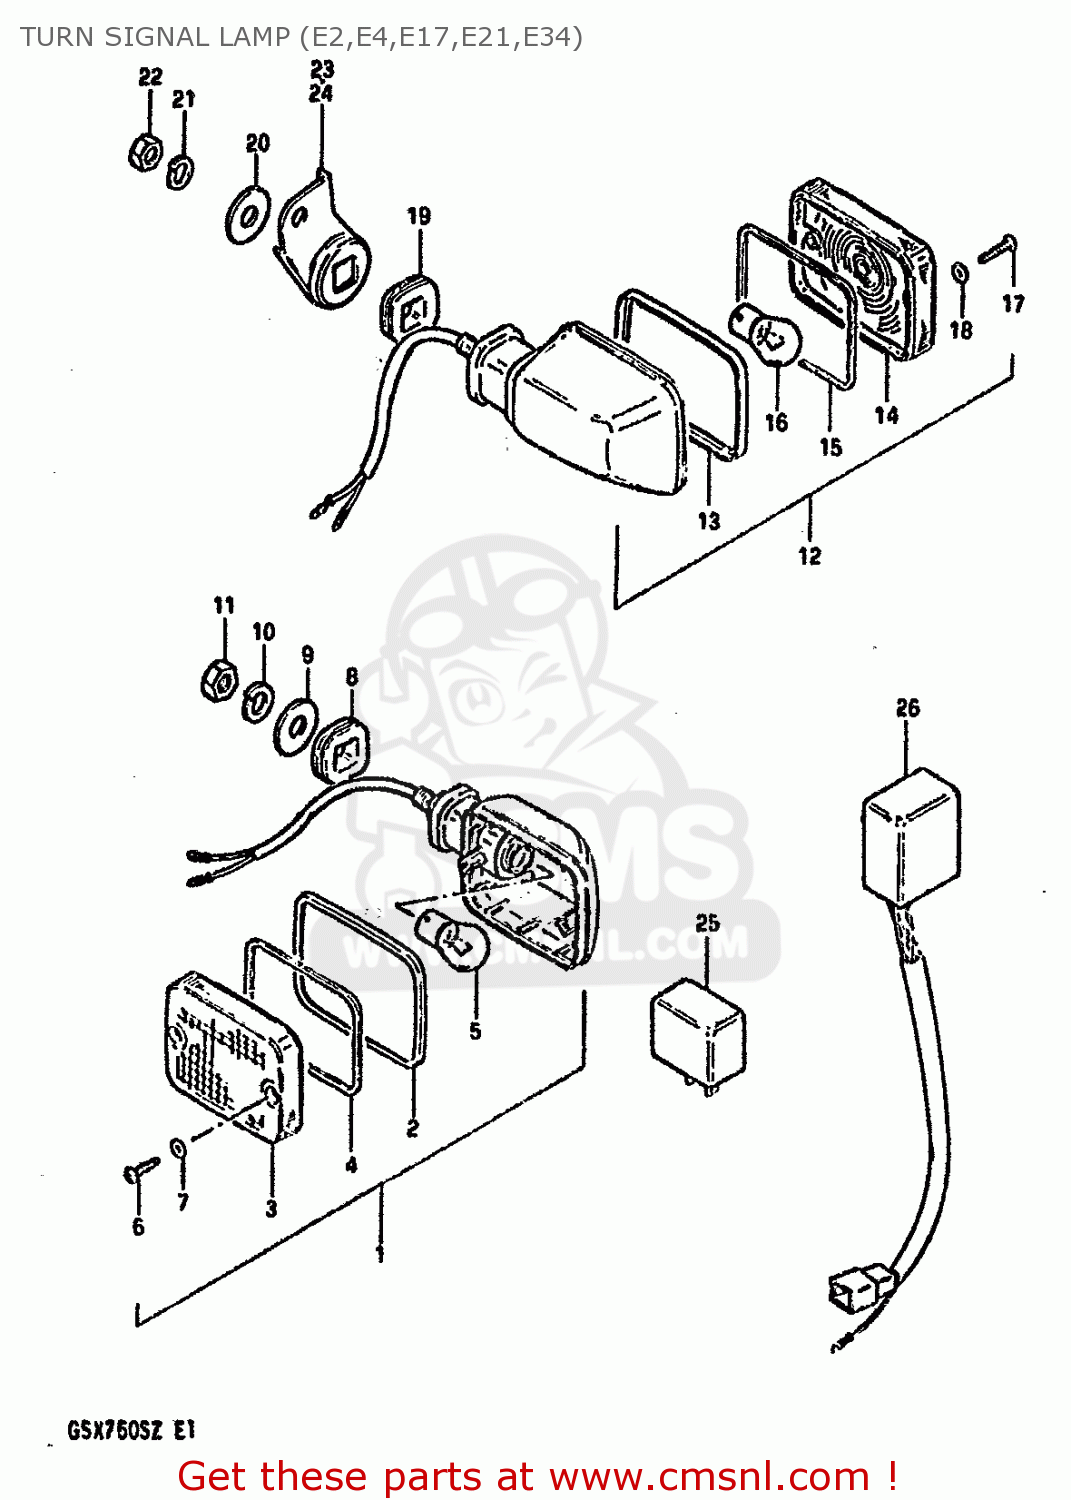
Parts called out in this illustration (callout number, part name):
1	LAMP ASSY,FR T
2	RIM
3	LENS
4	GASKET (NAS)
5	BULB 12V 21W
6	SCREW
7	GASKET (NAS)
8	CUSHION
9	WASHER (10.5X30X2.3)
10	LOCK WASHER
11	NUT
12	LAMP, REAR TURN SIGNAL
13	RIM
14	LENS
15	GASKET (NAS)
16	BULB 12V 21W
17	SCREW
18	GASKET (NAS)
19	CUSHION
20	WASHER (10.5X30X2.3)
21	LOCK WASHER
22	NUT
23	BRACKET,RR TURNSIGNAL LAMP,R
24	BRACKET,RR TURNSIGNAL LAMP,L
25	RELAY ASSY,TURNSIGNAL
26	UNIT,TURN SIGNAL CONTROL
